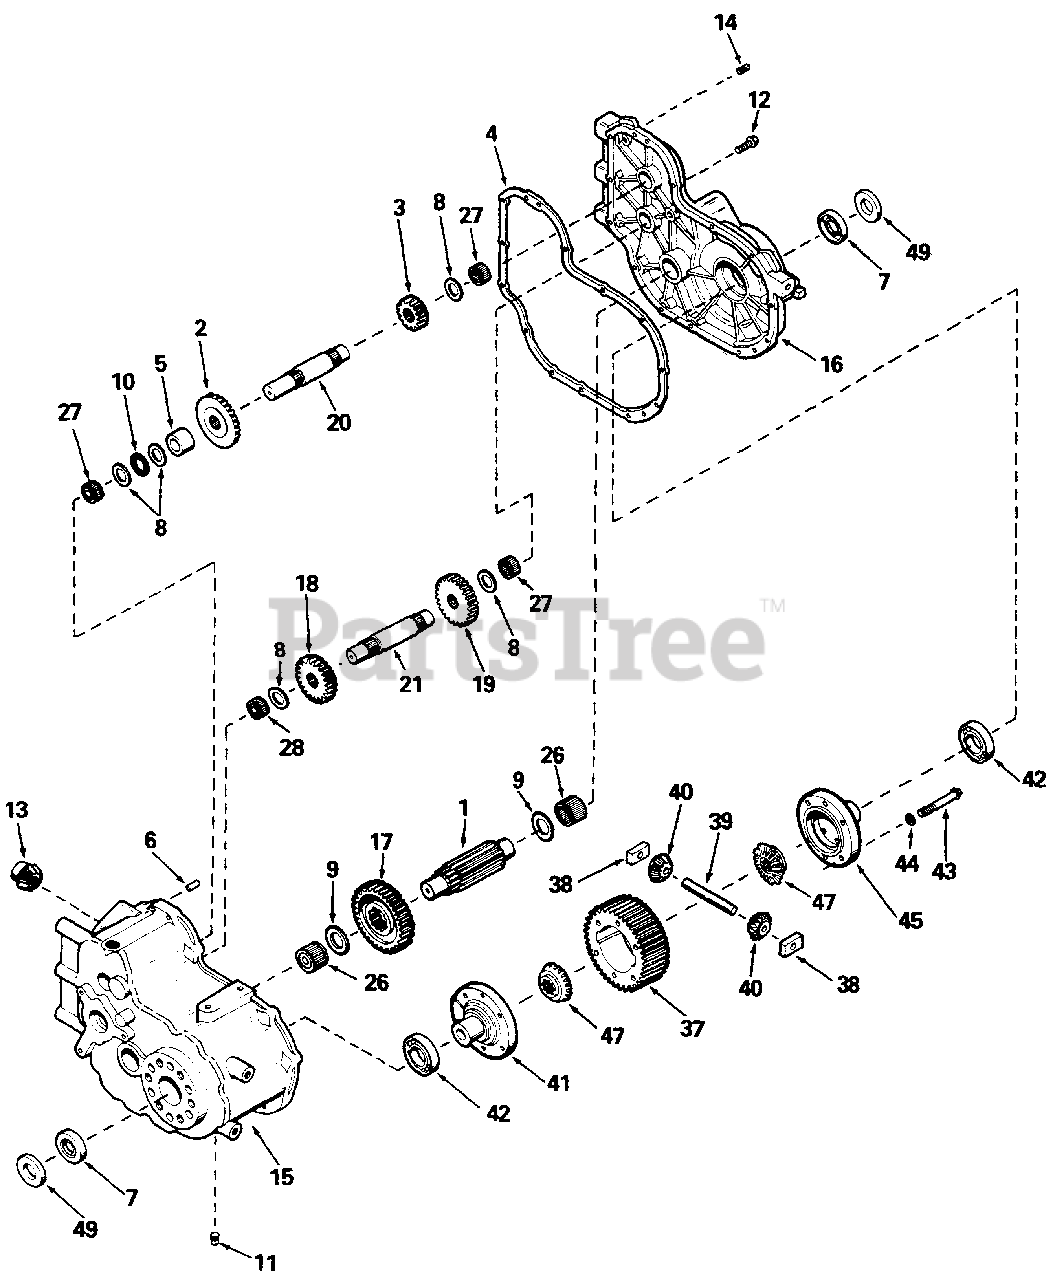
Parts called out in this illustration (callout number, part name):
1	PINION, Output
2	GEAR, Bevel (30 teeth)
3	GEAR, Spur (16 teeth)
4	GASKET, Case & Cover
5	SPACER, 1-5/8 OD x 1-1/64 ID x 55/64 thick
6	PIN, Dowel
7	SEAL, Oil
8	WASHER, Thrust, 1.542 OD x 1.007 ID x .060 thick
9	WASHER, Thrust, 1.917 OD x 1.257 ID x .060 thick
10	BEARING, Thrust
11	PLUG, Magnetic drain, 3/8-18
12	SCREW, Hex Hd. Threadforming 5/16-18 x 1
13	PINION, Bevel
14	PLUG, Pipe, 1/8-27
15	CASE ASSY., Transaxle (Incl. Ref. Nos. 26, 27 & 28)
16	COVER ASSY., Transaxle (Incl. Ref. Nos. 26 & 27)
17	GEAR, Output (33 teeth)
18	GEAR, Spur (17 teeth)
19	GEAR, Spur (27 teeth)
20	SHAFT, Counter
21	SHAFT, Brake
26	BEARING, Needle
27	BEARING, Needle
28	BEARING, Needle
37	GEAR, Ring
38	BLOCK, Drive
39	PIN, Drive
40	PINION, Bevel
41	CARRIER, Differential
42	BEARING, Ball
43	SCREW, Hex Flanged Hd., 3/8-16 x 2-3/4
44	LOCKWASHER, 3/8"
45	CARRIER, Differential
47	GEAR, Bevel
49	SPACER, 2-1/8 OD x 1-5/32 ID x 3/8 thick
